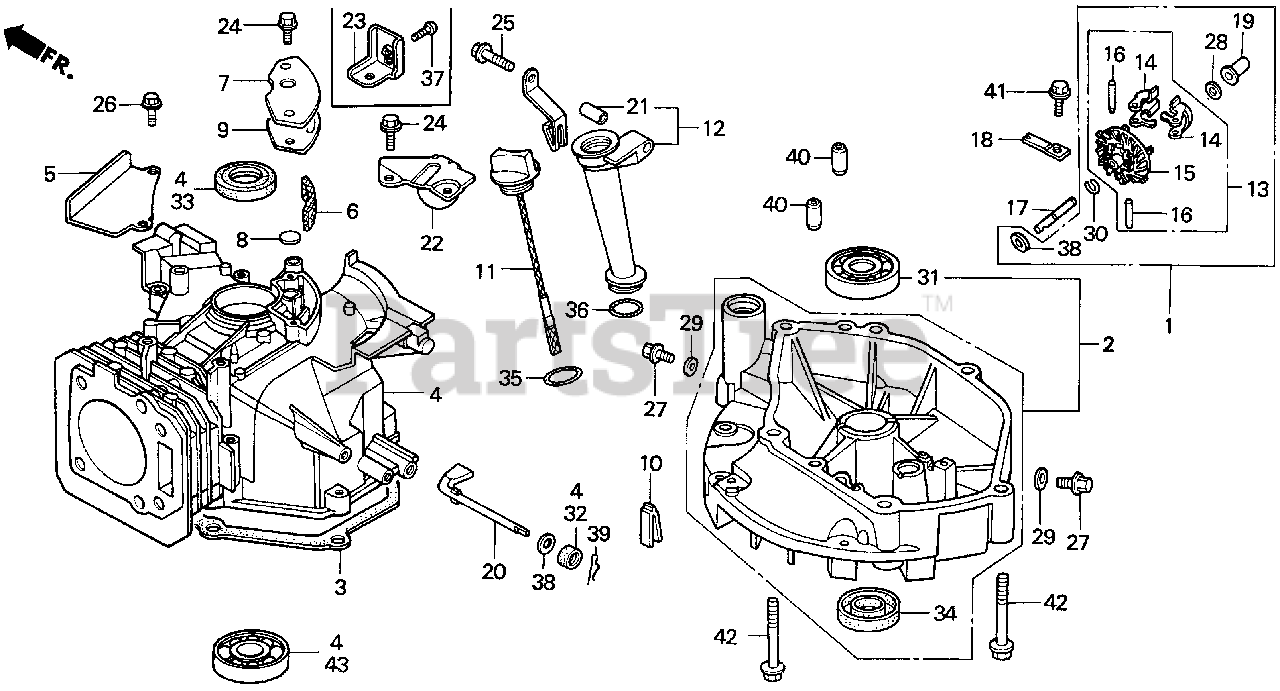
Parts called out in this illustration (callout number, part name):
1	GOVERNOR KIT
2	PAN ASSY., OIL
3	GASKET, OIL PAN
4	CYLINDER ASSY.
6	FILTER, BREATHER
7	COVER, BREATHER
8	VALVE, BREATHER
9	GASKET, BREATHER COVER
10	RUBBER, OIL RETURN
11	DIPSTICK, OIL
12	EXTENSION, OIL FILLER (106MM)
13	GOVERNOR ASSY.
14	WEIGHT, GOVERNOR
15	HOLDER, GOVERNOR WEIGHT
16	PIN, GOVERNOR WEIGHT
17	SHAFT, GOVERNOR HOLDER
18	PLATE, GOVERNOR SHAFT HOLDER
19	SLIDER, GOVERNOR
20	SHAFT, GOVERNOR ARM
21	COLLAR, EXTENSION
22	STAY, TANK
23	BASE, HOLDER
24	BOLT, FLANGE (6X14)
25	BOLT, FLANGE (6X32)
27	BOLT, DRAIN PLUG
28	WASHER, THRUST (6MM)
29	WASHER, DRAIN PLUG (10.2MM)
30	CLIP, GOVERNOR HOLDER
31	BEARING, RADIAL BALL
32	OIL SEAL (6X11X4)
33	OIL SEAL (25X38X7)
33	OIL SEAL (25X38X7) (ARAI)
34	OIL SEAL (25.4X40X7)
35	O-RING (26X2.7)
36	O-RING (22.5X2.2)
37	SCREW, PAN (5X8)
38	WASHER, PLAIN (6MM)
39	PIN, LOCK (8MM)
40	PIN A, DOWEL (8X14)
41	BOLT, FLANGE (6X12)
42	BOLT, FLANGE (8X50)
43	BEARING, RADIAL BALL (6205)
